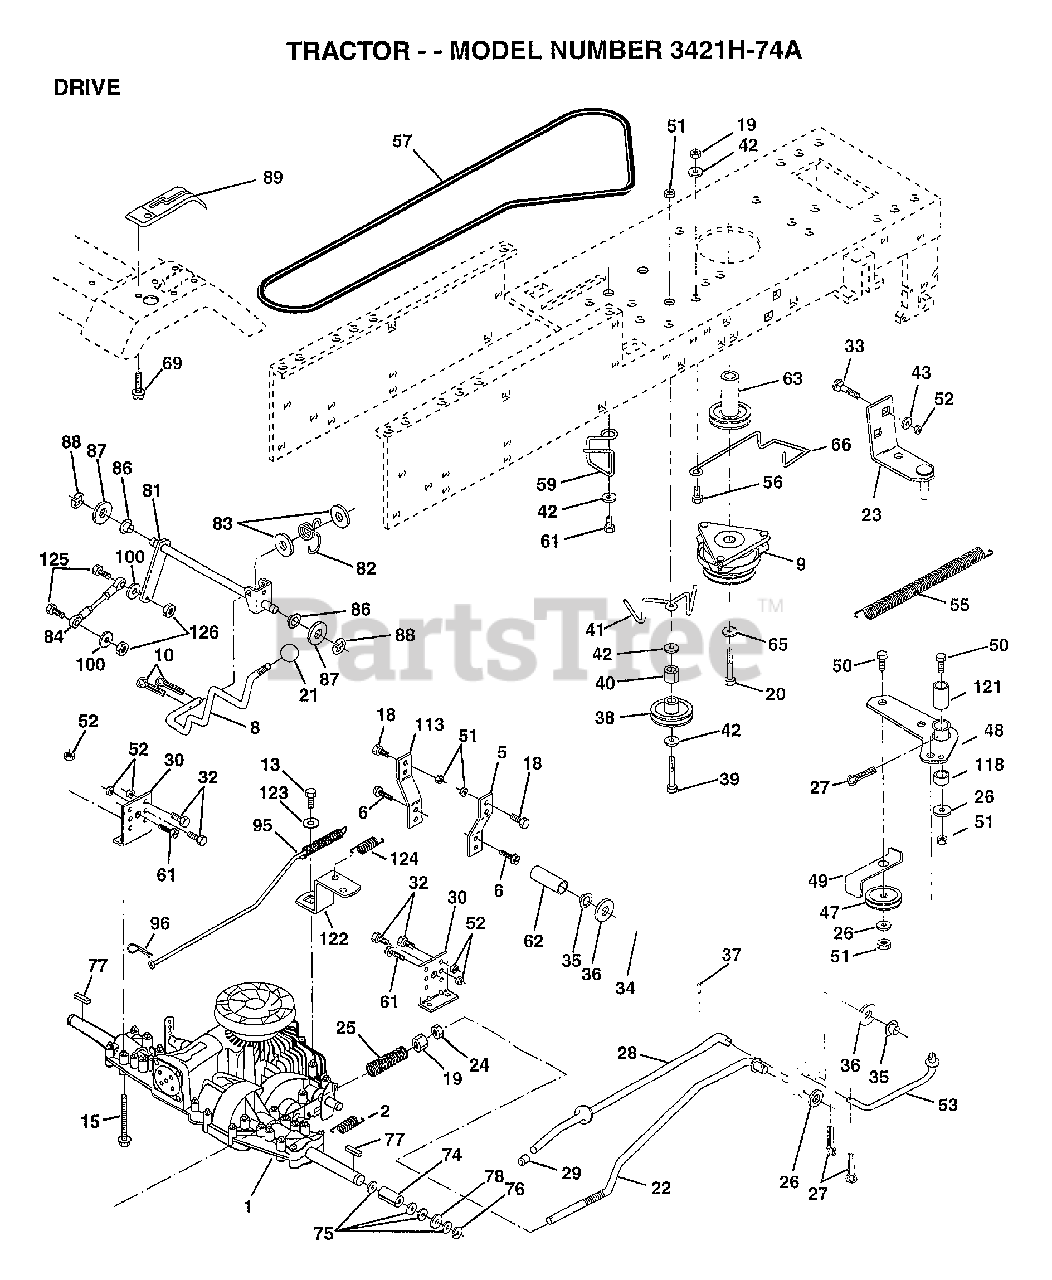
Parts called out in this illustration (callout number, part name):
1	TRANSAXLE, PEERLESS
2	SPRING.BRAKE.RETU
5	STRAP TORQUE
6	SCREW
8	ROD SHIFT FEND LT
10	PIN COTTER 1/8
13	BOLT.1/4-28.W/PAT
15	BOLT.HX.FLG.5/16
17	WASHER
18	BOLT
19	NUT
20	BOLT.7/16-20X4.25
21	KNOB T (1/2-HOLE)
22	BRAKE ROD
23	BRACKET.ASM.MTG
24	NUT
25	SPRING ROD LT
26	WASHER
27	COTTER PIN
28	ROD.BRAKE.PARK.LT
29	PLUNGER CAP T
30	TRANSAXLE MTG BKT
32	BOLT
33	BOLT
34	SHAFT ASM-PEDAL F
35	NYLON BEARING
36	WASHER LT
38	PULLEY.IDLER.FLAT
39	BOLT
40	SPACER T
42	WASHER
43	WASHER T
48	BELLCRANK ASM
49	RETAIN BELT
53	"LINK, CLUTCH T"
55	"SPRING, RETURN LT"
57	"V-BELT,GRD DRIVE"
59	KEEPER BELT CNTSP
61	SCREW
62	PEDAL COVER T
63	PULLEY CLU ELEC
65	LOCKWASHER
66	KEEPER-BELT
69	SCREW HEXWSH H-L
74	"SPACER AXLE,PVST"
75	WASHER
76	E-RING LT
77	SQUARE KEY
78	WASHER
81	SHAFT ASM CROSS
82	"SPRING,TORSION"
83	WASHER
84	"ROD TIE, PVST 20"""
86	BUSHING
87	WASHER D
88	KLIP RING
95	ROAD ASM BYPASS
96	RETAINER M
100	WASHER M
113	"STRAP,TORQUE"
118	SPACER-BELLCRANK
121	NYLINER-CLUTCHING
122	"PLATE-BYPASS,PVST"
124	SPRING RETURN
